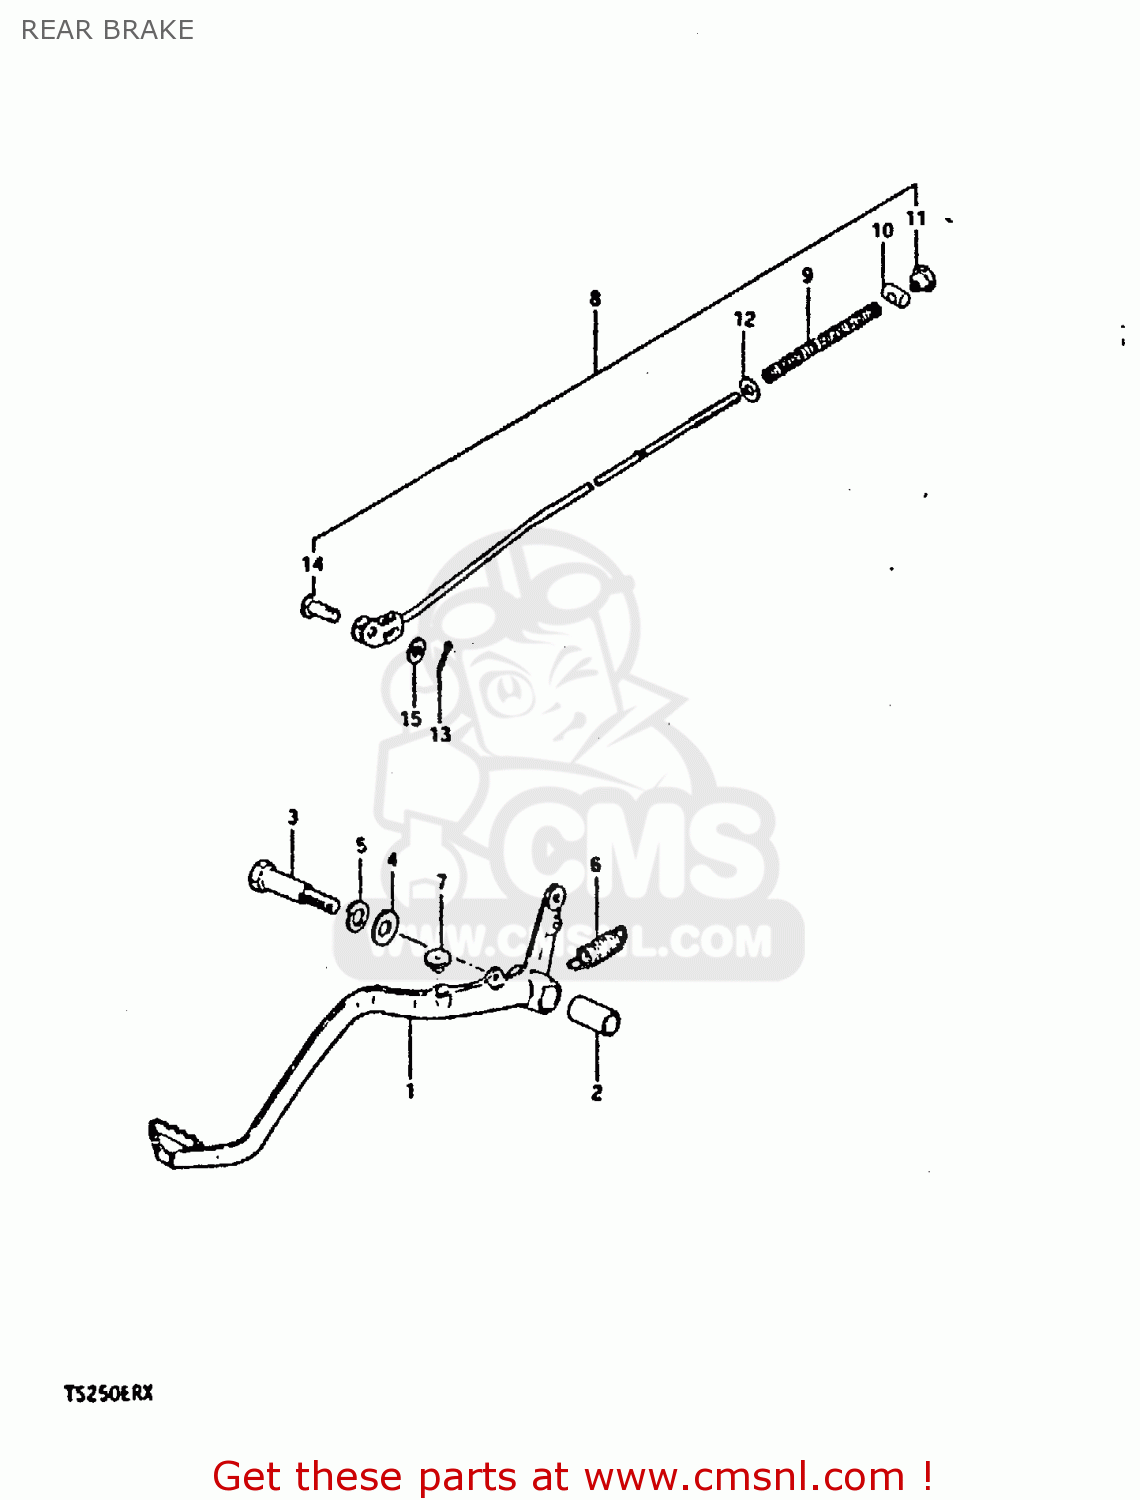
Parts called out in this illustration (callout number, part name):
1	PEDAL,BRAKE
2	SPACER(10.5X16X30)
3	BOLT
4	WASHER
5	LOCK WASHER
6	SPRING
7	STOPPER,BRAKE PEDAL
8	ROD ASSEMBLY,REAR BRAKE
9	SPRING
10	PIN(11X18)
11	NUT
12	WASHER
13	PIN 20X20
14	PIN(L:13.5)
15	WASHER
